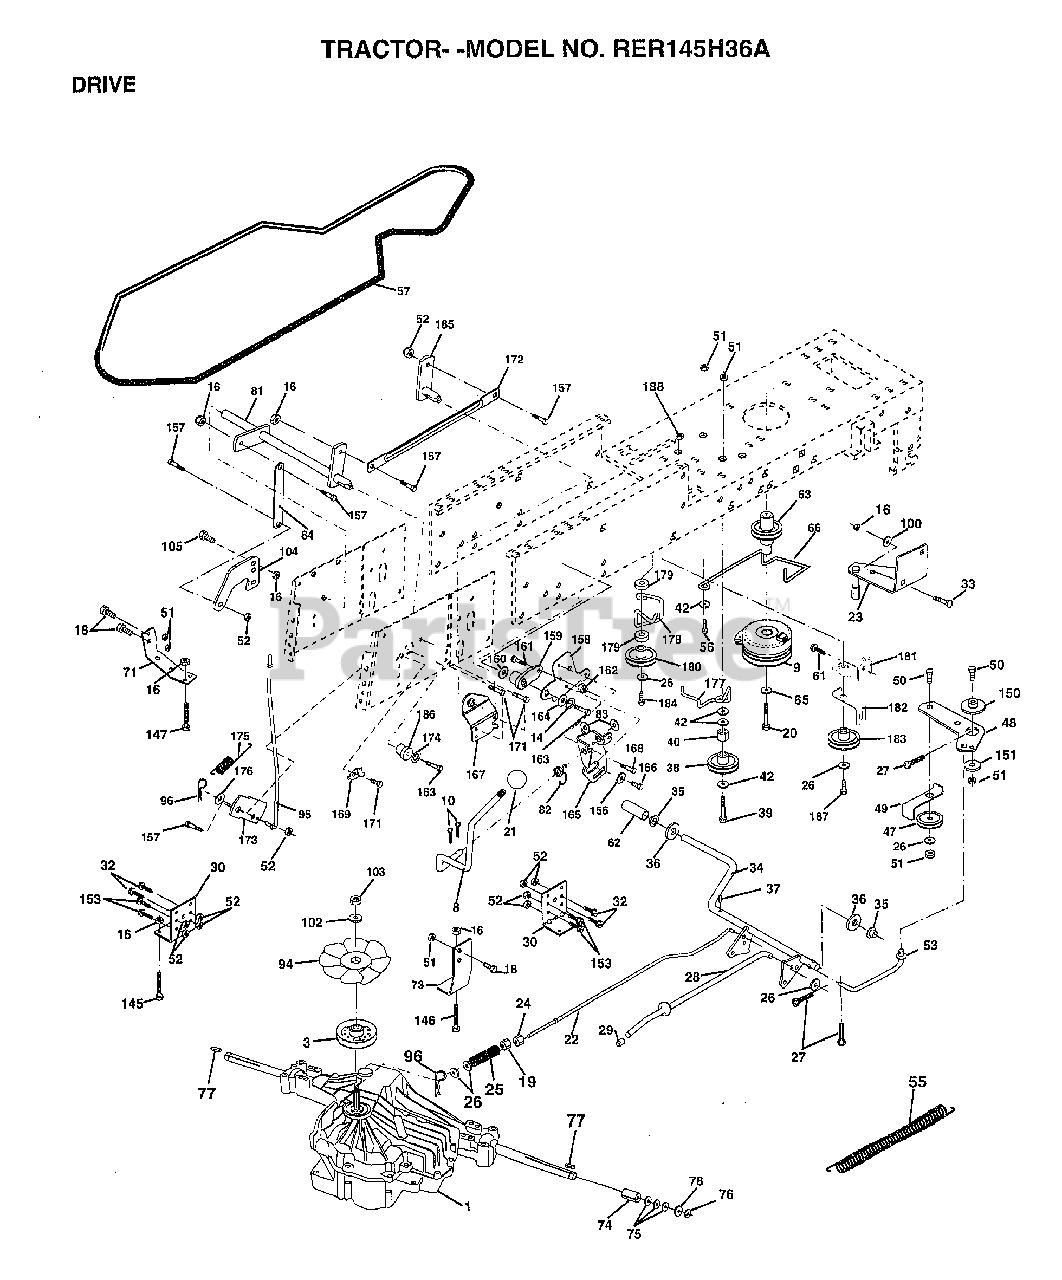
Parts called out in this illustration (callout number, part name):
3	PULLEY.TRANSAXLE
8	ROD.SHIFT.FENDER.ADJ.LT.CRD
9	CLUTCH.ELEC.EVX
10	PIN COTTER 1/8
14	LOCKWASHER
16	NUT
18	BOLT
19	NUT
20	BOLT.7/16-20X4.25
21	KNOB T (1/2-HOLE)
22	ROD.BRAKE.CRD
23	BRACKET.CLUT.MTG.
24	NUT
25	SPRING ROD LT
26	WASHER
27	COTTER PIN
28	ROD.BRAKE.PARK.LT
29	PLUNGER CAP T
30	TRANSAXLE MTG BKT
32	BOLT
33	BOLT
34	SHAFT.ASM.PEDAL.FOOT.CRD
35	NYLON BEARING
36	WASHER LT
38	PULLEY.FLAT.IDLER
39	BOLT
40	SPACER T
42	WASHER
48	BELLCRANK.CLUTCH
49	RETAIN BELT
53	"LINK, CLUTCH T"
55	"SPRING, RETURN LT"
57	"V-BELT.KEV.112"""
61	SCREW
62	PEDAL COVER T
63	PULLEY.CLUTCH.EVX
65	LOCKWASHER
66	KEEPER-BELT
71	STRAP TORQ LH HYD
73	"STRAP-TORQUE,RH"
74	SPACER SPLIT
75	WASHER
76	E-RING LT
77	SQUARE KEY
78	WASHER
81	ASM.SHAFT
82	"SPRING,TORSION"
83	WASHER
84	LINK.TRANSAXLE
94	"FAN 7"" HYDRO"
95	CNTRL.ASM.BYPASS.HYDRO
96	RETAINER M
100	WASHER M
102	WASHER BELLEVILLE
104	ARM CONTROL HYDRO
105	SCREW CAP 5/16-18
145	BOLT.HEX.FLGHD
146	BOLT.HEX.FLGHD.
147	BOLT.HEX.FLGHD
150	BUSHING.BELLCRANK.GRD.DR
151	WASHER
156	WASHER.SRRTD.5/16
157	"BOLT,SHOULDER"
158	BRKT.SHIFT.MOUNT
159	HUB.SHIFT
160	WASHER
161	BOLT T
164	WASHER.5/8X.281X10GA
165	BRKT.PIVOT.LEVER
166	SCREW.5/16-18X5/8
167	BRKT.SUPT.SHIFT.CRD
168	BOLT.SHOULDER.5/16-18X.561
169	PLATE.FASTENING
171	SCREW LT
172	LINK.SHAFT.CRD.HYDRO
173	BKRT.HYDRO.BYPASS.CRD
175	SPRING.BYPASS.CRD
176	WASHER
177	KEEPOER.FLAT.IDLER
178	KEEPER.BELT.IDLER
179	WASHER
180	PULLEY.FLAT
181	BRKT.IDLER.GRD.DR.CRD
182	"KEEPER.BELT.2.5"".OD.CRD"
183	PULLEY.V-IDLER
184	SCREW.HXWSH.3/8
185	SHAFT.ASM.SHIFTER.FRT.CRD
186	HUB.TAPERED.ROUND.CRD
187	SCREW
